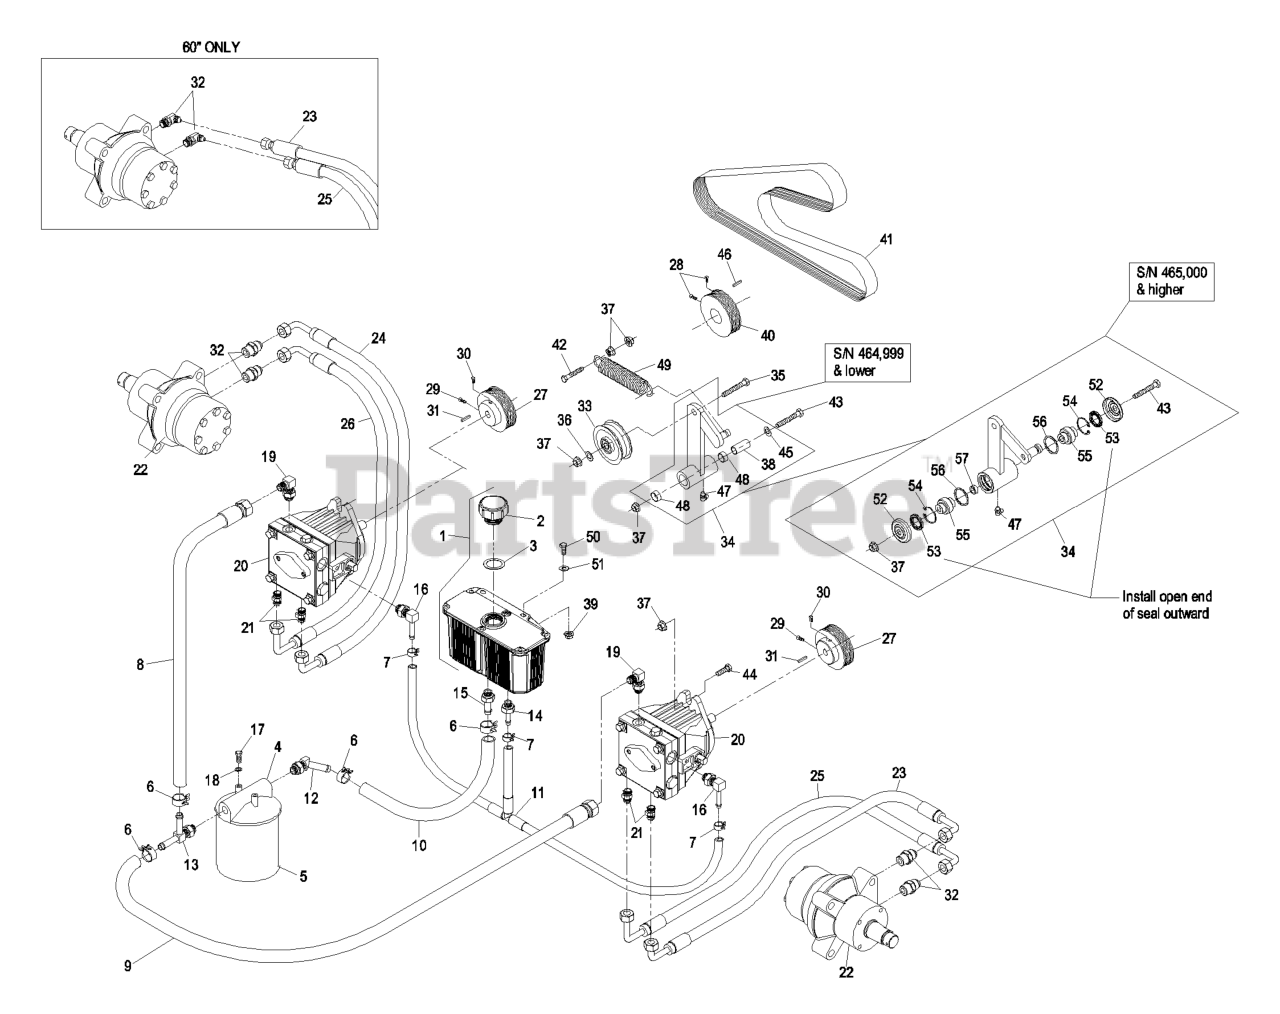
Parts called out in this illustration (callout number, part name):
1	HYD RESERVOIR ASM
2	Cap-Reservoir, HYD
3	GASKET-CAP
4	HEAD-FILTER
6	CLAMP-HOSE
7	CLAMP-HOSE
8	HYD HOSE ASM
9	HYD HOSE ASM
10	HOSE-HYD
11	HYD HOSE ASM
12	FITTING-BARBED, 45 DEG
13	ADAPTER-RUN, TEE
14	ADAPTER-STRAIGHT
15	ADAPTER-STRAIGHT
16	ELBOW-90 DEG
17	SCREW-HH
18	WASHER-LOCK
19	FITTING-ELBOW, 90 DEG
20	PUMP-HYD
21	FITTING-STRAIGHT
22	MOTOR-WHEEL
23	HYD HOSE ASM
24	HYD HOSE ASM
25	HYD HOSE ASM
26	HYD HOSE ASM
28	SCREW-SET
29	SCREW-SET
30	SCREW-SET
32	FITTING-STRAIGHT
33	SHEAVE-IDLER
34	KIT,PUMP IDLER LZ
35	SCREW-HH
36	WASHER-FLAT
37	NUT-HHF, WHIZ
38	BUSHING-PIVOT, IDLER
41	BELT,POLY-V 5K
42	SCREW-HH
43	SCREW-HH
44	SCREW-HH
45	WASHER-FLAT
46	KEY-SQUARE
47	FITTING-GREASE, 90 DEG
48	SLEEVE-BEARING
50	SCREW-HH
51	WASHER-FLAT
52	GUARD-TOP
53	SEAL-LIP, SINGLE
54	RING-SNAP
55	BEARING-SPHERICAL
56	O-RING
57	SPACER
